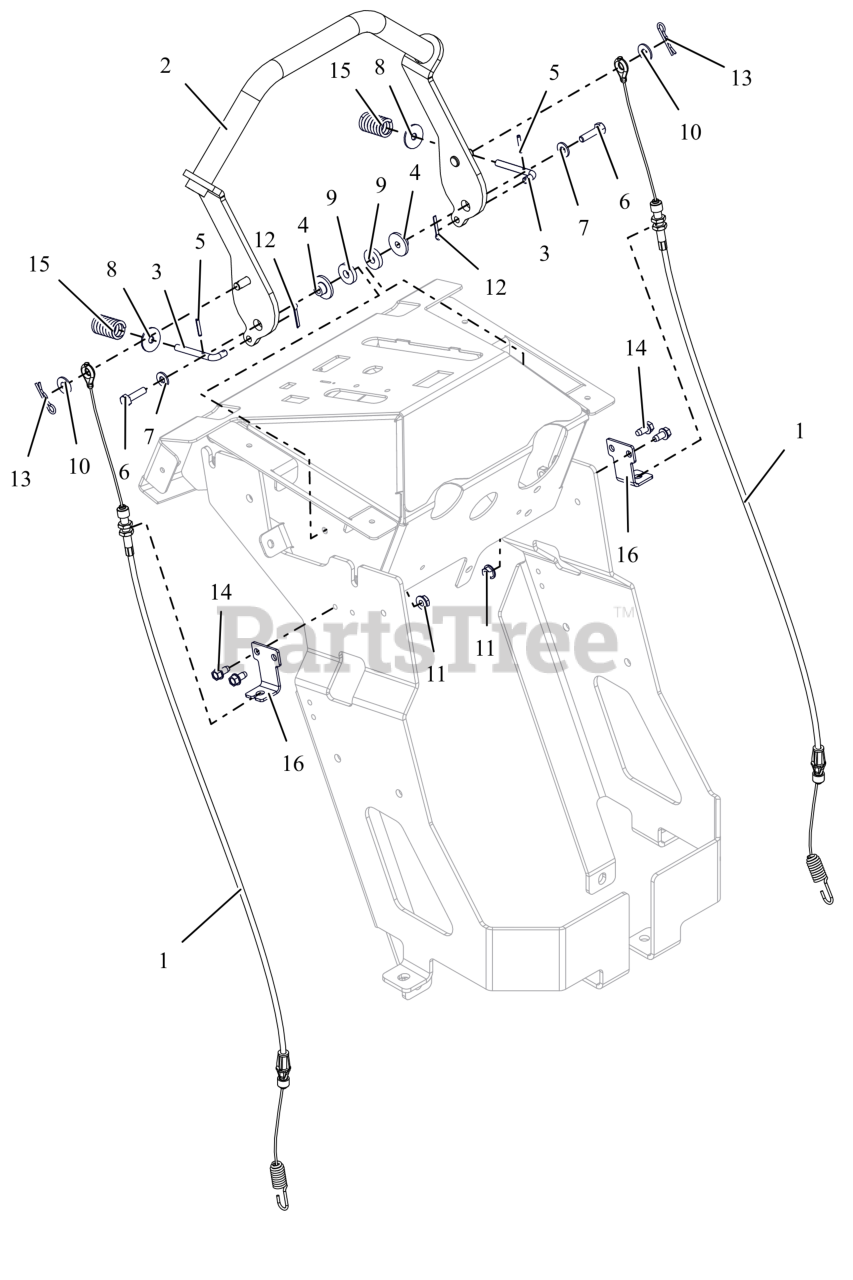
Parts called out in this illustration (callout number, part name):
1	CABLE, PRO WALK BRAKE
2	WLDMT, BRAKE (BLACK)
3	ROD, OVER CENTER BRAKE
4	BSHG-FLG .265X.477X.375X1.00
5	PIN-ROLL .125X.75
6	BLT,HEX .25-20X1.00 G5 ZCC
7	WSHR,FLT .281X.625X.065 ZCC
8	WSHR,FLT .281X1.000X.063 ZCC
9	WSHR, FLT .328X.870X.179 ZCC
10	WSHR, FLT .312X.734X.065 ZCC
11	NUT-LK-CTR-FLG .25-20 ZC120
12	PIN,CTR .12X.75EXTPRSQCT ZC120
13	PIN-HAIR INT .08X.38X1.42 YWZC
14	SCR-TAP .25-20X.50 HWH ZCC
15	SG-COMP .125X.781X1.250
16	BRKT, BRAKE CABLE (BLACK)
